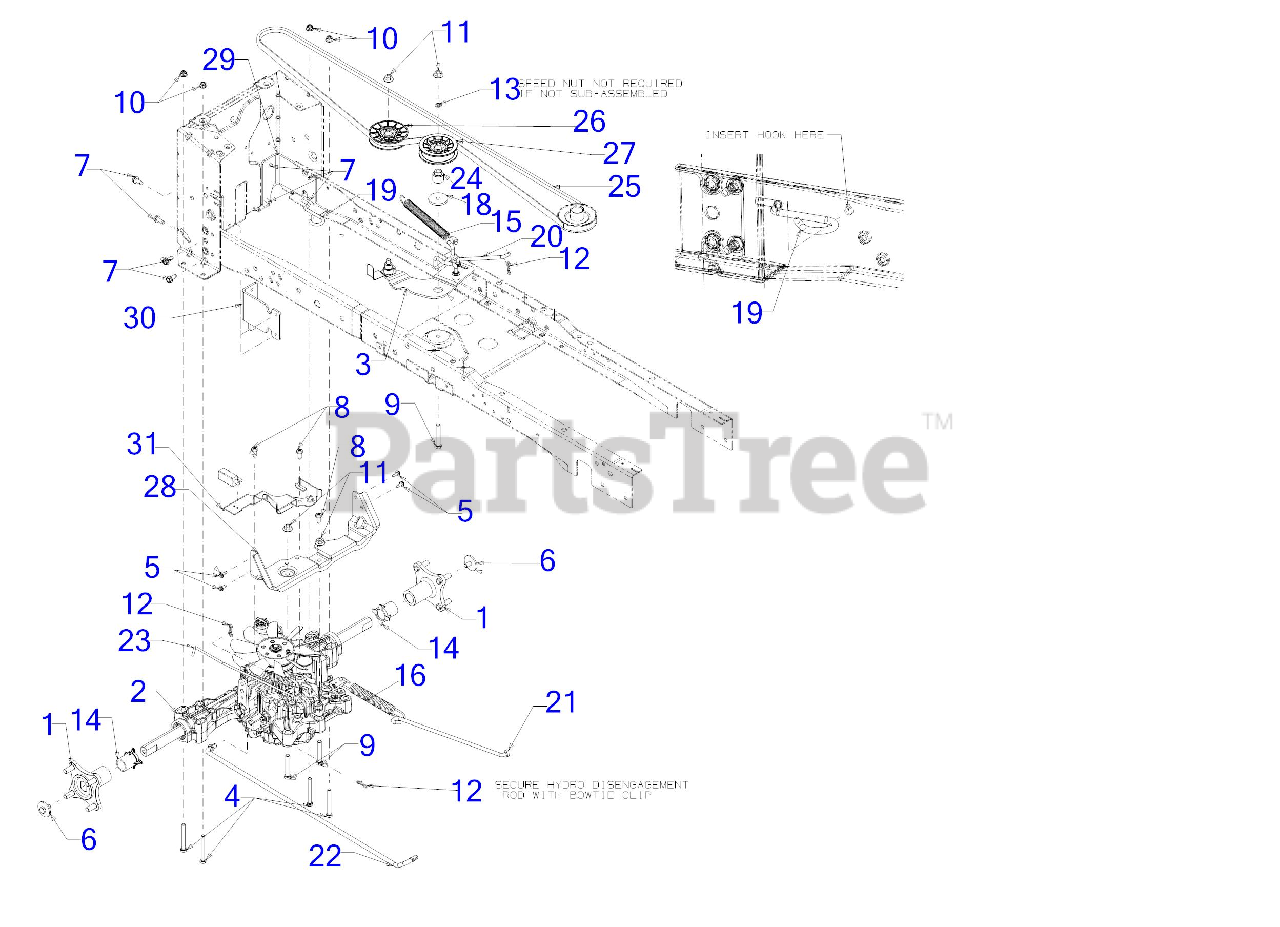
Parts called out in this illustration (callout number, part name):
1	WHEEL HUB ASSEMBLY
2	TRANSMISSION ASSEMBLY
3	IDLER BRACKET ASSEMBLY
4	HEX SCREW 5/16-18 x 2.75
5	SCREW M6-1 x .625
6	SCREW 3/8-16 x .75 GR5.1
7	SCREW 5/16-18 x .750
8	SCREW 5/16-18 x .750
9	SCREW 3/8-16 x 2.25 GR5
10	FLANGE LOCK NUT 5/16-18
11	FLANGE LOCK NUT
12	BOW TIE COTTER PIN 1/4-5/16
13	PUSH NUT
14	AXLE SLEEVE 1.02 ID x 1.60 LG
15	EXTENSION SPRING .790 DIA x 8.41
16	EXTENSION SPRING 0.90 DIA x 8.14
18	SHOULDER SPACER
19	DECK SPRING HOOK
20	IDLER BRACKET LINK ROD
21	BRAKE ROD
22	HYDRO CONTROL ROD
23	HYDRO DISENGAGEMENT ROD
24	SHOULDER SPACER
25	V-BELT A SEC x 91.10
26	V-IDLER PULLEY 3.56 OD
27	FLAT IDLER PULLEY 3.00 OD
28	TRANSMISSON MOUNTING BRACKET
